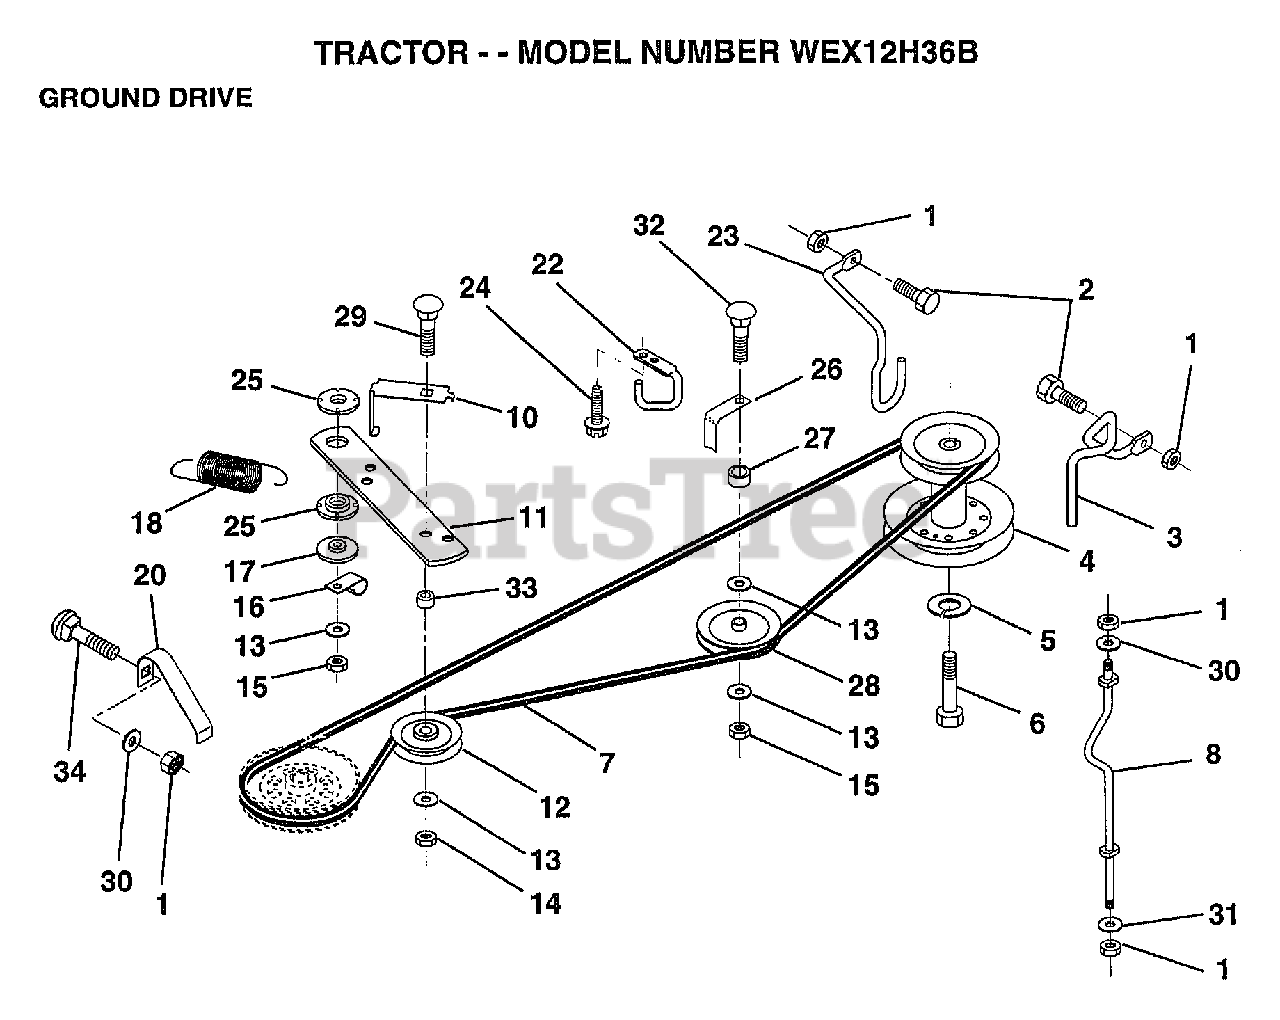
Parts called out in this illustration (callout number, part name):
1	NUT
2	BOLT
3	KEEPER.BELT.FRT.
4	PULLEY.ENGINE.LR
5	LOCKWASHER
6	HEX BOLT
7	BELT-V.DRV.77.75
8	KEEPER.BELT.HYDRO
10	KEEPER.BELT.GRD.
11	ARM-IDLER.DR.GRND
12	PULLEY.IDLER.FLAT
13	WASHER
14	LOCKNUT
16	"CLIP,INSULATOR"
17	SPACER
20	KEEPER.BELT.LH
22	"KEEPER,FRA DR BEL"
23	KEEPER MOWER LH
24	SCREW
25	BUSHING.NYLON
26	KEEPER.BELT.IDLER
27	SPACER.625X.843
28	PULLEY.IDLER.V.GR
29	BOLT RDHD 3/8-16
30	WASHER
31	WASHER M
32	BOLT
34	BOLT
